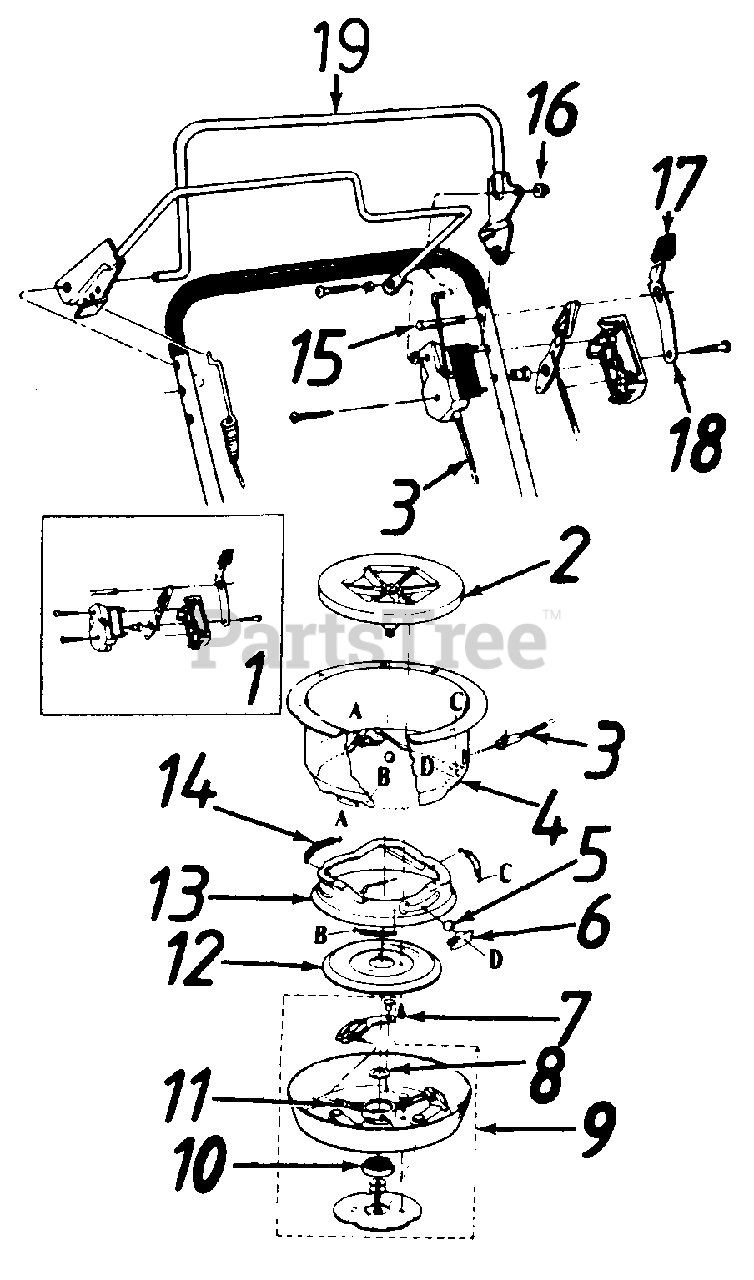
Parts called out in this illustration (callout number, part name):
1	Kit-Control Housing Comp.
2	Fan Adapter
3	Clutch Cable
4	Clutch Housing
5	Steel Ball
6	Ball Block
7	Hex Tap Scr. 1/4-20 x .75"
8	Fl-Wash. .69" I.D. x 1.06"
9	Clutch Blade Housing Ass'y.
10	Ball Bearing
11	Compression Spring
12	Clutching Cone
13	Brake Cup Cone
14	Extension Spring
15	Lock Pin
16	Push Cap
17	Knob
18	Lockout Lever
19	Control Handle
